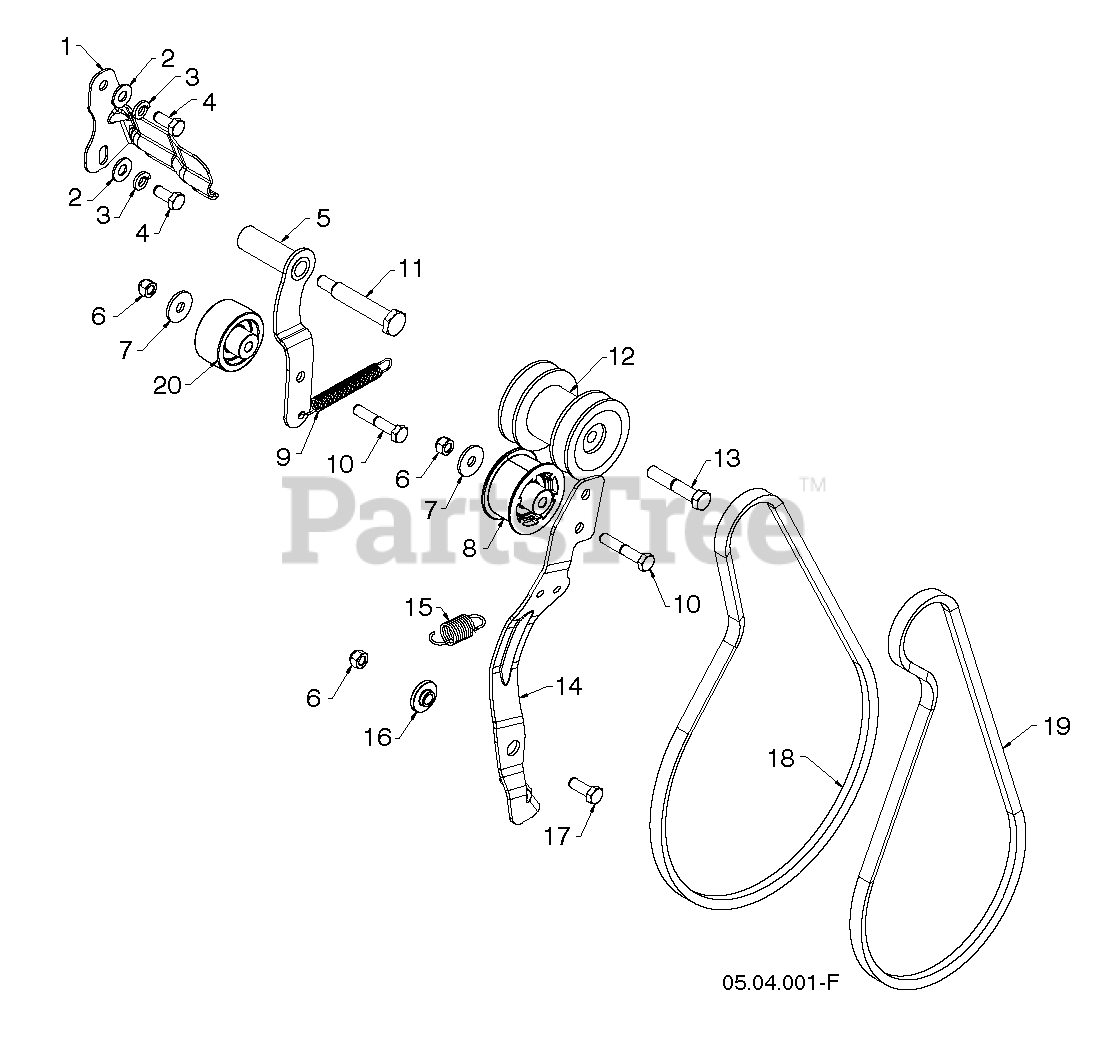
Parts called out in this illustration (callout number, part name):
1	Belt Keeper Bracket
2	WASHER M
3	LOCKWASHER
4	SCREW 5/16-24 X .75 GR5
5	Drive Weldment Idler Arm, Hot 008
6	NUT.71038.31-18.HEX.NYLOCK
7	STEEL WASHER
8	Idler Pulley, 2.00 W Spa
9	Idler Arm Return Spring
10	BOLT, HEX 5/16-18X1-3/4
11	Hex Head Shoulder Bolt, 5/16-24 X 2.25
12	Impeller/Drive Assembly Pulley
13	BOLT.BLADE
14	Impeller Idler Arm Bracket
15	Impeller Idler Arm Return Spring
16	Idler Pivot Bushing
18	Belt, 4L X 38.19
19	Low Crank Impeller Belt
20	Flange Idler Pulley, 2 O/Spacer
